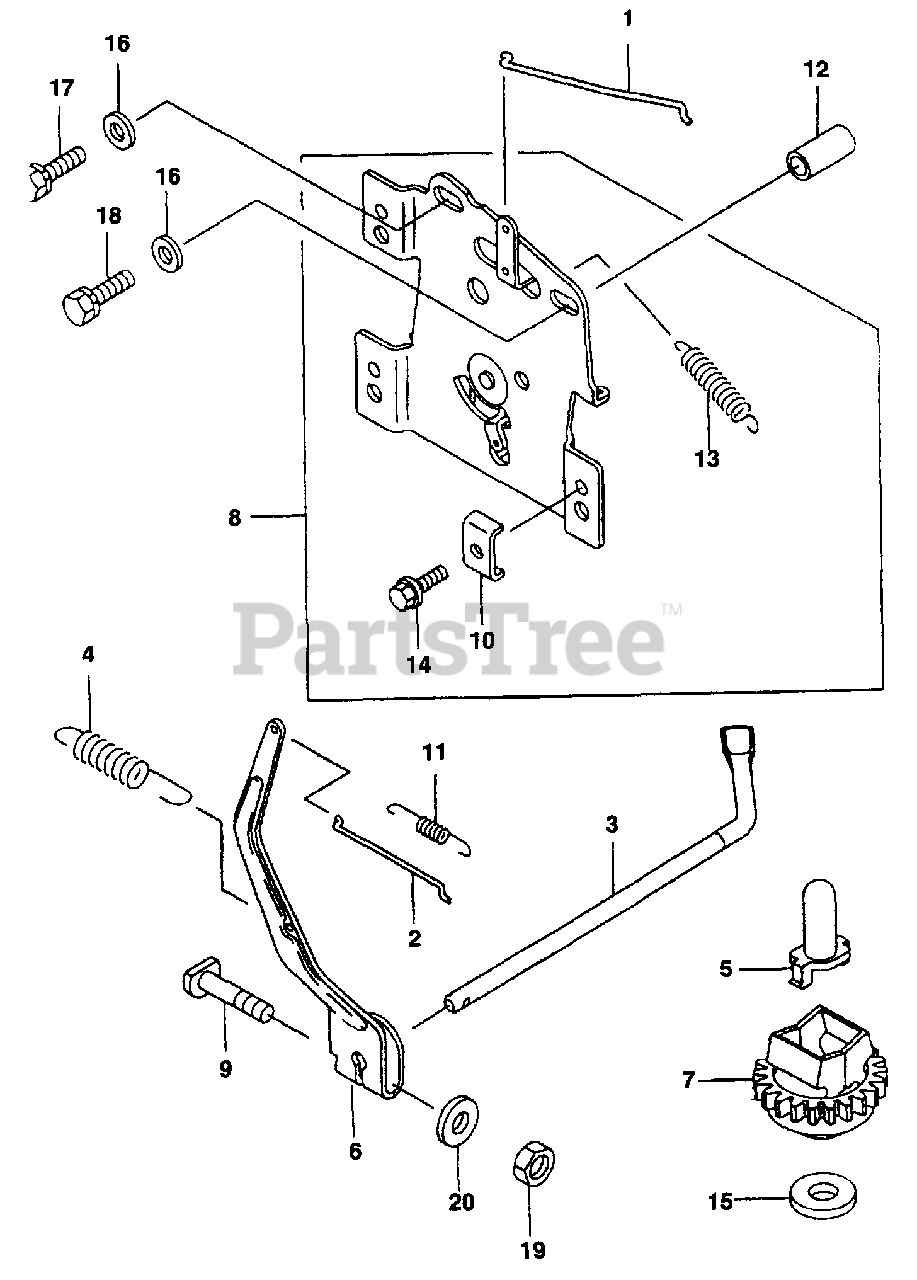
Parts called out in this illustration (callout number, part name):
4	Governor Spring
7	Governor Ass'y
8	Control Panel Comp
12	Collar, 6.8 x 10 x 20.5
17	WS Bolt Upset
18	WS Bolt Upset
19	Hex Nut
20	Plain Washer
